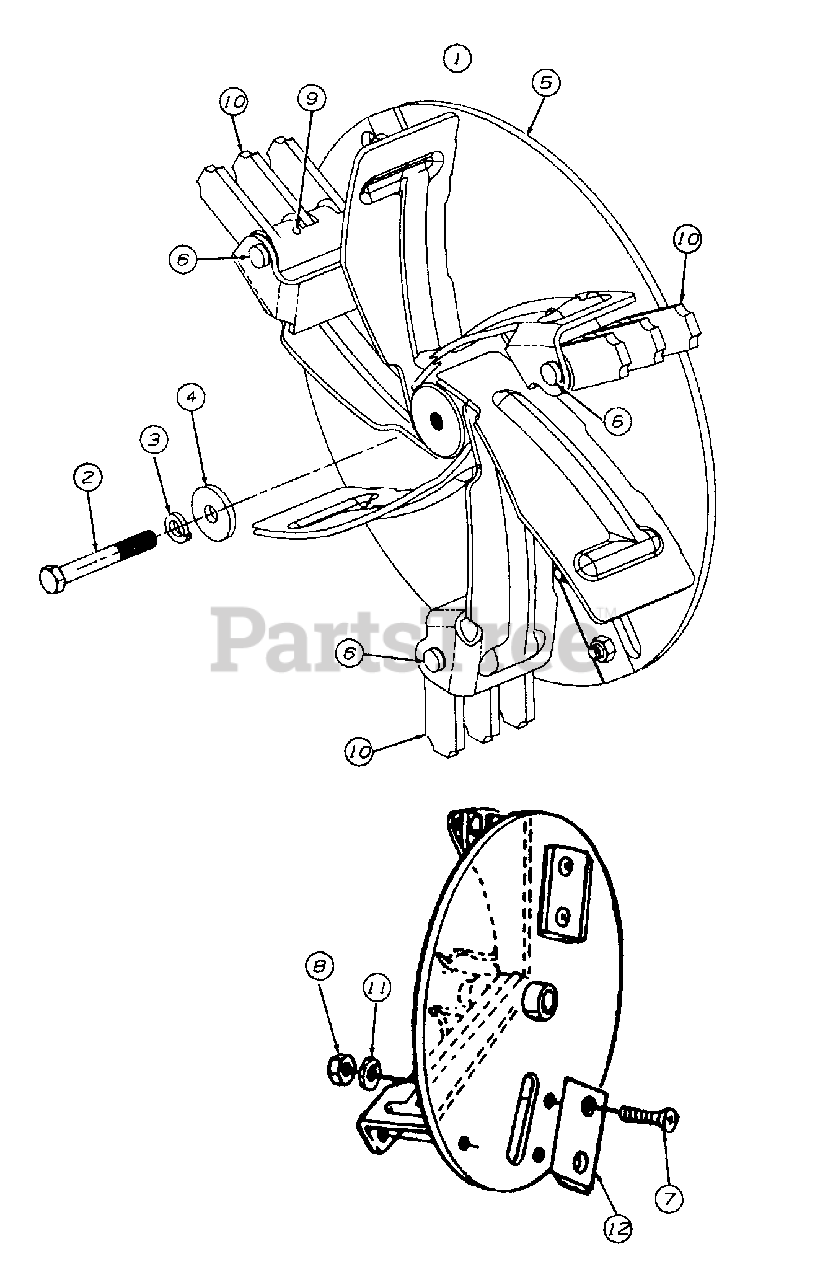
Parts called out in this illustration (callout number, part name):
1	IMPELLER ASS'Y COMP.
2	SCREW-HEX
3	WASHER-LOCK
4	WASHER-FLAT
5	IMPELLER
6	PIN-CLEVIS
7	SCREW-FLAT HEAD
8	NUT-HEX LOCK
9	PIN-ROLL SPRING
10	BLADE-FLAIL
11	WASHER-LOCK
12	BLADE-CHIPPER
